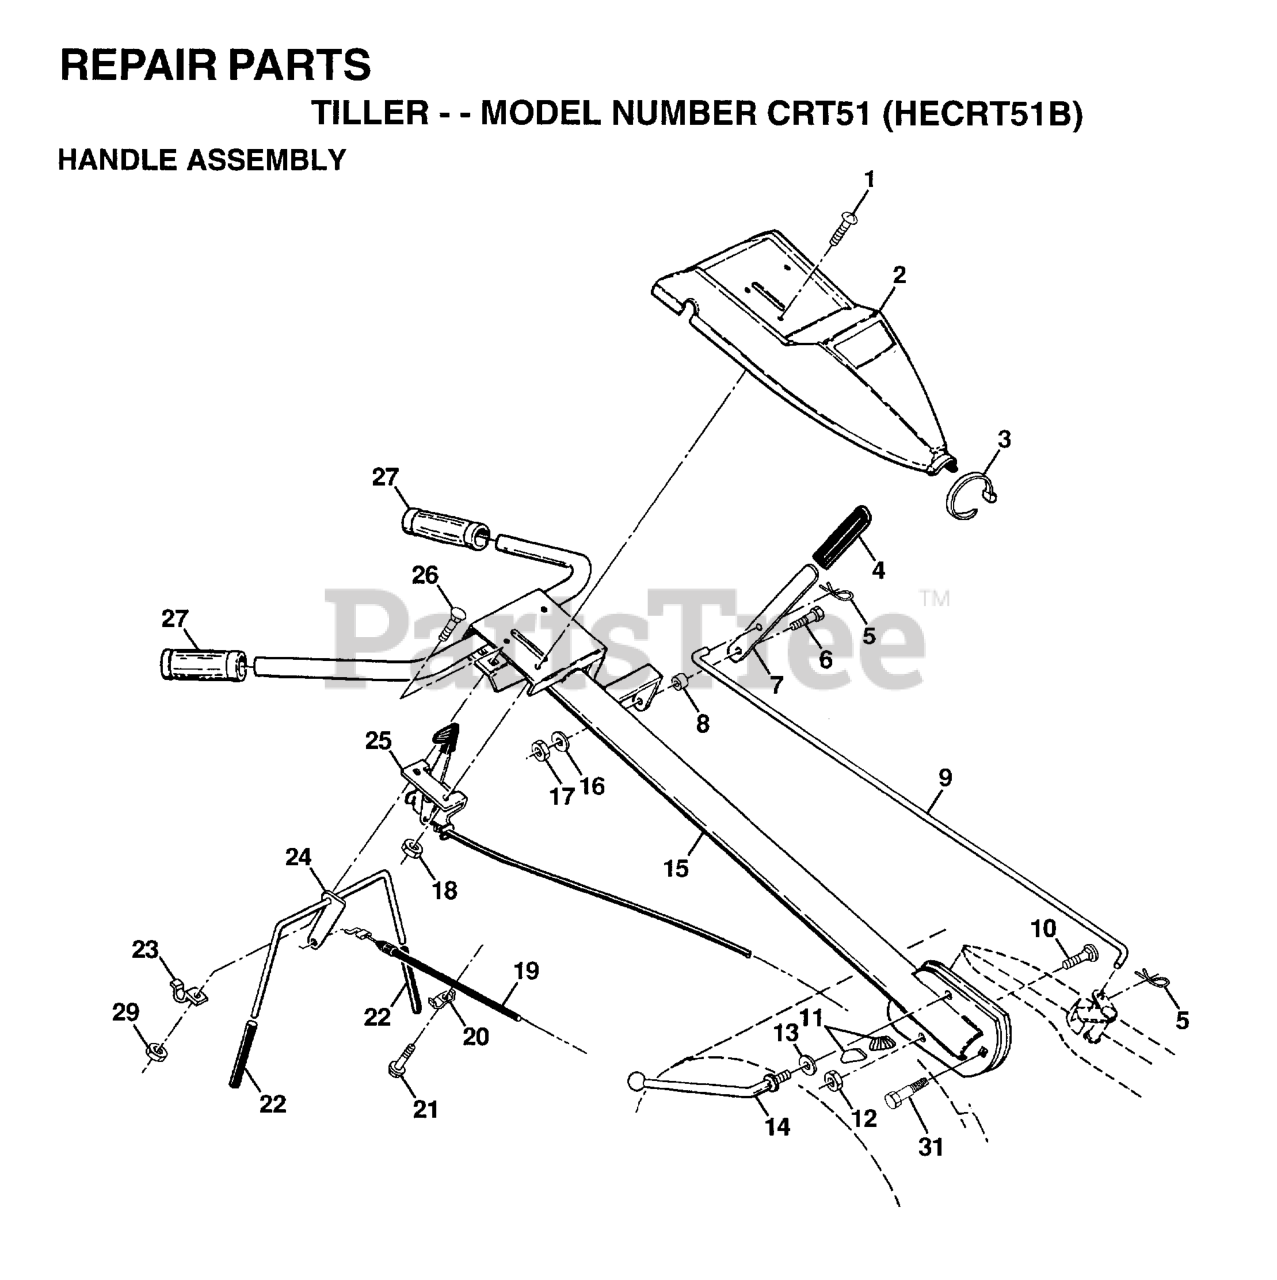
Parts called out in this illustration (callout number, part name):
1	SCREW.PNHD.10-24
3	TIE CABLE CRT
4	GRIP T
5	RETAINER M
6	SHOULDER BOLT ST
7	SHIFT HANDLE CRT
8	GROMMET.RUBBER.CRT.TILLER
9	SHIFT ROD CRT
10	BOLT D
11	LOCK.HANDLE.CRT
12	LOCKNUT
13	WASHER CRT
14	LEVER.LOCK.CRT
15	HANDLE
16	LOCKWASHER
17	NUT
18	NUT **
19	CABLE, CLUTCH 48 "Z"
20	CONDUIT.CLIP.PLATED
21	TAPPING SCREW
22	GRIP BAR CRT(1)
23	CLAMP.BAR.CRT.BLACK
24	BAR ASSY CONTROL
25	CONT,THROTTLE
27	KIT.GRIP.HANDLE.5.00.BLK.VINYL
29	NUT
31	BOLT.PIVOT
